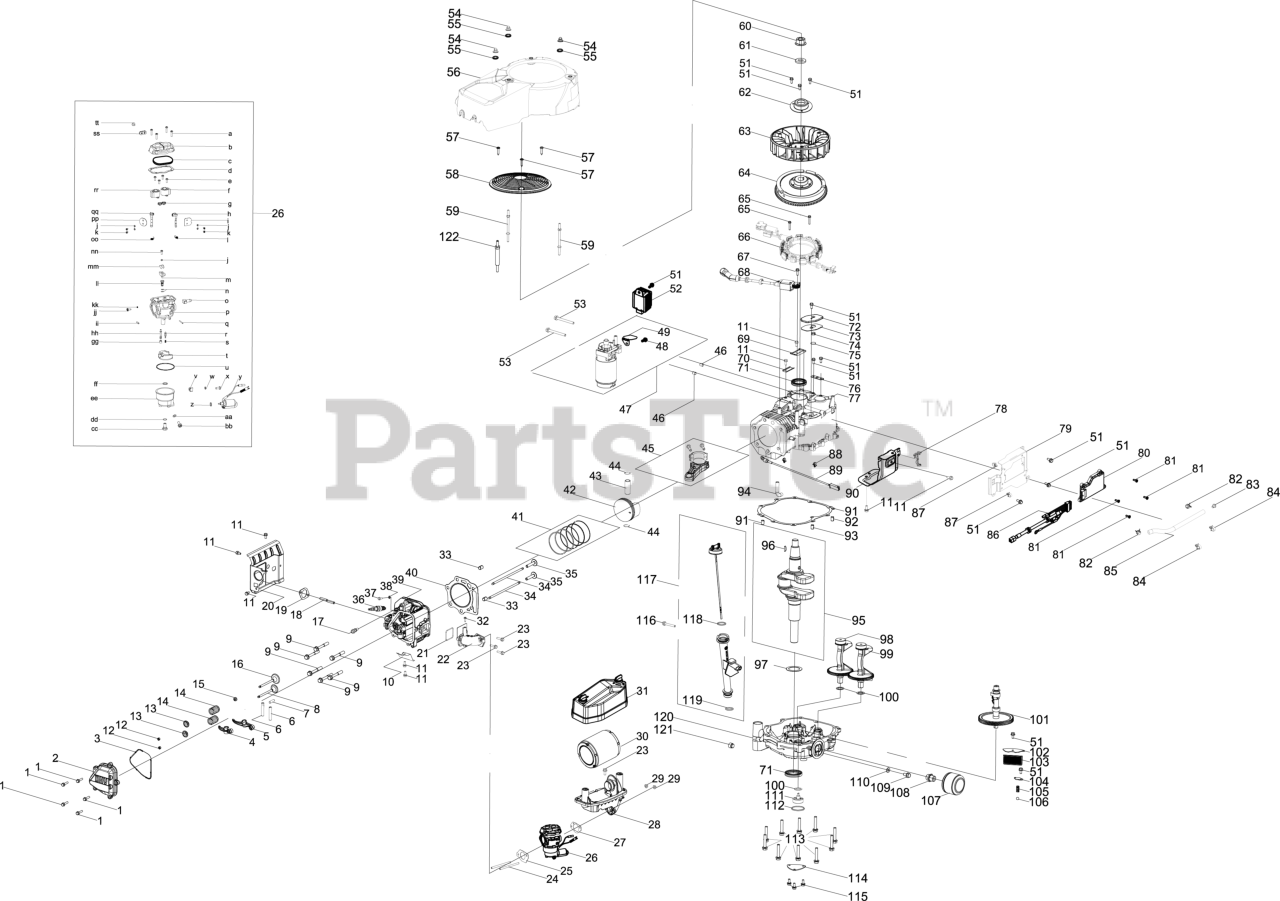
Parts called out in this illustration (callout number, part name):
1	BOLT M6-1 x 25 GR8.8
2	VALVE COVER
3	VALVE COVER GASKET
4	ROCKER ARM (EXHAUST)
5	ROCKER ARM (INTAKE)
6	ROCKER ARM SHAFT
7	CAMSHAFT PIN
8	EXHAUST VALVE
9	BOLT M10-1.25 x 70
11	BOLT M6-1 x 12 GR8.8
12	VALVE CAP
13	VALVE SPRING SEAT
14	VALVE SPRING
15	INTAKE VALVE SEAL
16	INTAKE VALVE
19	EXHAUST GASKET
20	SHROUD - LEFT SIDE
21	INTAKE PIPE RING
22	INTAKE PIPE
23	BOLT M6 x 22
24	STUD M6-1.00 x 92
25	INTAKE GASKET
26	CARBURETOR
27	AIR FLTER GASKET
28	INTAKE MANIFOLD
30	AIR FILTER W/PREFILTER
30	Cub Cadet AIR FILTER/PRE-FILTER
30	Genuine Factory Parts AIR FILTER
30	Troy-Bilt AIR FILTER (05066)
31	AIR FILTER COVER
32	SELF TAPPING SCREW 4.8 x 16
34	SINGLE PUSH ROD
36	SPARK PLUG (F6RTC/RN11YC/BPR6ES)
37	BOLT M5-.8 x 10
38	FLAT WASHER: 5.3 x 10 x 1
39	CYLINDER HEAD
40	CYLINDER HEAD GASKET
41	PISTON RING SET
43	PISTON PIN
44	PISTON PIN SNAP RING
45	CONNECTING ROD ASSEMBLY
47	STARTER
48	BOLT M6 x 16
49	STARTER SHIELD BRACKET
51	BOLT M6-1 x 14 GR8.8
52	REGULATOR ASSEMBLY
53	BOLT M8-1.25 x 80
54	ACORN NUT
57	BOLT 5.5 x 25
58	DEBRIS SHIELD
60	NUT M20 x 1.5
61	WASHER 20.5 x 5 x 40
62	FLYWHEEL OULET SHIELD
63	COOLING FAN
65	BOLT M5 x 28
66	CHARGING COIL
67	BOLT-M6-1 x 28 GR8.8
68	IGNITION COIL ASSEMBLY
69	WIRE PLATE
70	BREATHER SCREEN
71	OIL SEAL 38 x 58 x 8
72	BREATHER COVER
73	BREATHER COVER GASKET
74	BREATHER VALVE SPRING
75	BREATHER VALVE
79	ECM MOUNT BRACKET
80	ELECTRONIC CONTROL MODULE
81	SCREW M4x12
82	HOSE CLAMP
84	FUEL LINE SUPPORT CLAMP
85	FUEL HOSE 6.3 x 12.5 x 250
86	WIRE HARNESS (EGOV)
87	PLASTIC SUPPORT CLAMP
88	WIRE SUPPORT CLAMP
89	TEMPERATURE SENSOR
90	SHROUD - RIGHT
91	CRANKCASE COVER GASKET
92	DOWEL PIN 9 X 14
93	DOWEL PIN
94	VENTING HOSE
95	CRANKSHAFT ASSEMBLY
96	FLYWHEEL KEY
97	WASHER 38.3 x 54 x 1
98	BALANCE SHAFT (LH)
99	BALANCE SHAFT (RH)
100	WASHER 17.2 x 26 x 1
102	FILTER COVER
103	FILTER SCREEN
104	PRESSURE RELEASE COVER
105	PRESSURE RELEASE SPRING
106	OIL PUMP STEEL BALL
107	ENGINE OIL FILTER
107	Cub Cadet OIL FILTER
107	Genuine Factory Parts OIL FILTER
107	Troy-Bilt OIL FILTER
108	SCREW JOINT OIL FILTER ADAPTER
109	BOLT M8 x 15
110	OIL DRAIN PLUG WASHER
111	OIL PUMP ASSEMBLY
113	BOLT M8 x 45
114	OIL SEPARATOR
115	SCREW M6-1 x 16
116	BOLT M6-1 x 45 CL5.8
117	DIPSTICK ASSEMBLY
120	CRANKCASE COVER
121	ENGINE PLUG 3/8 NPT
